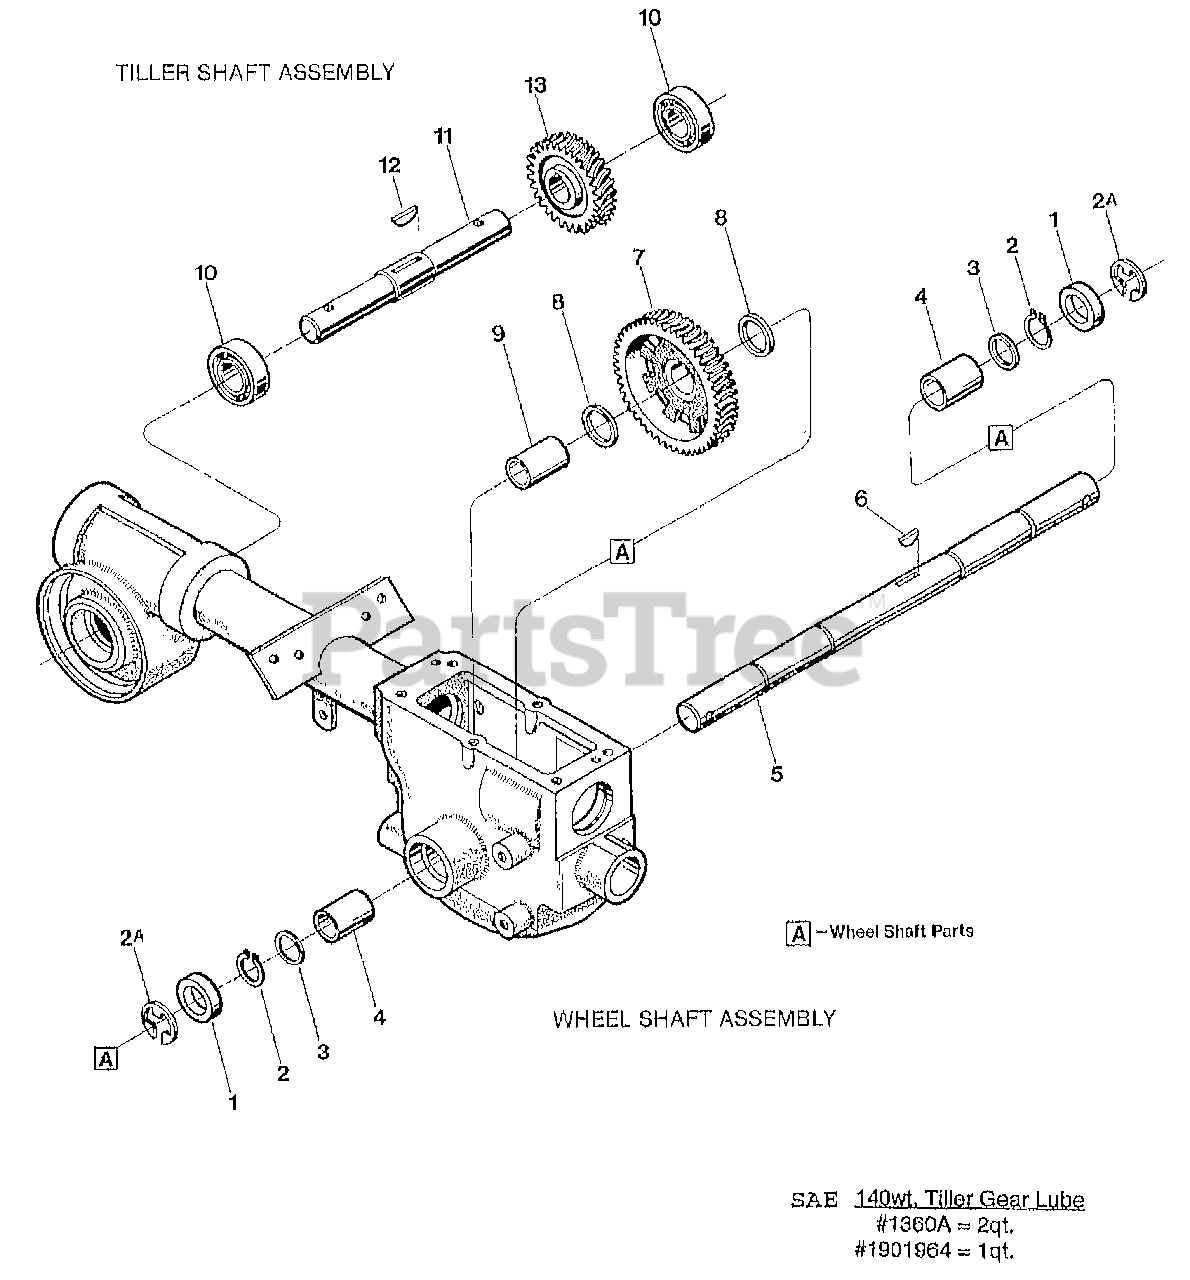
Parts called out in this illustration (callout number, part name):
1	SEAL-OIL WHEELSHAFT
2	RING-HEAVY EXT .906 ID
2A	RING-RETAINING 5133-989
3	SHIM-1.375X1.015X.062
3	SHIM-1.375X1.015X.03
3	SHIM-1.375X1.015X.015
3	SHIM-1.375X1.015X.01
4	BUSHING-1.25X1.005X1.5
5	ASSM-WHEELSHAFT W/KEY (INCL. 6)
6	KEY-HI PRO .25X.938
7	GEAR-MACH (WORM GEAR)
8	SHIM-1.234X1.015X.01
9	SPACER-WHEEL SHAFT
10	BEARING-BALL
11	SHAFT-W/KEY (TILLER) (INCL. 12)
12	KEY-WOODRUFF .25X1.12
13	GEAR-TILLER MACH
